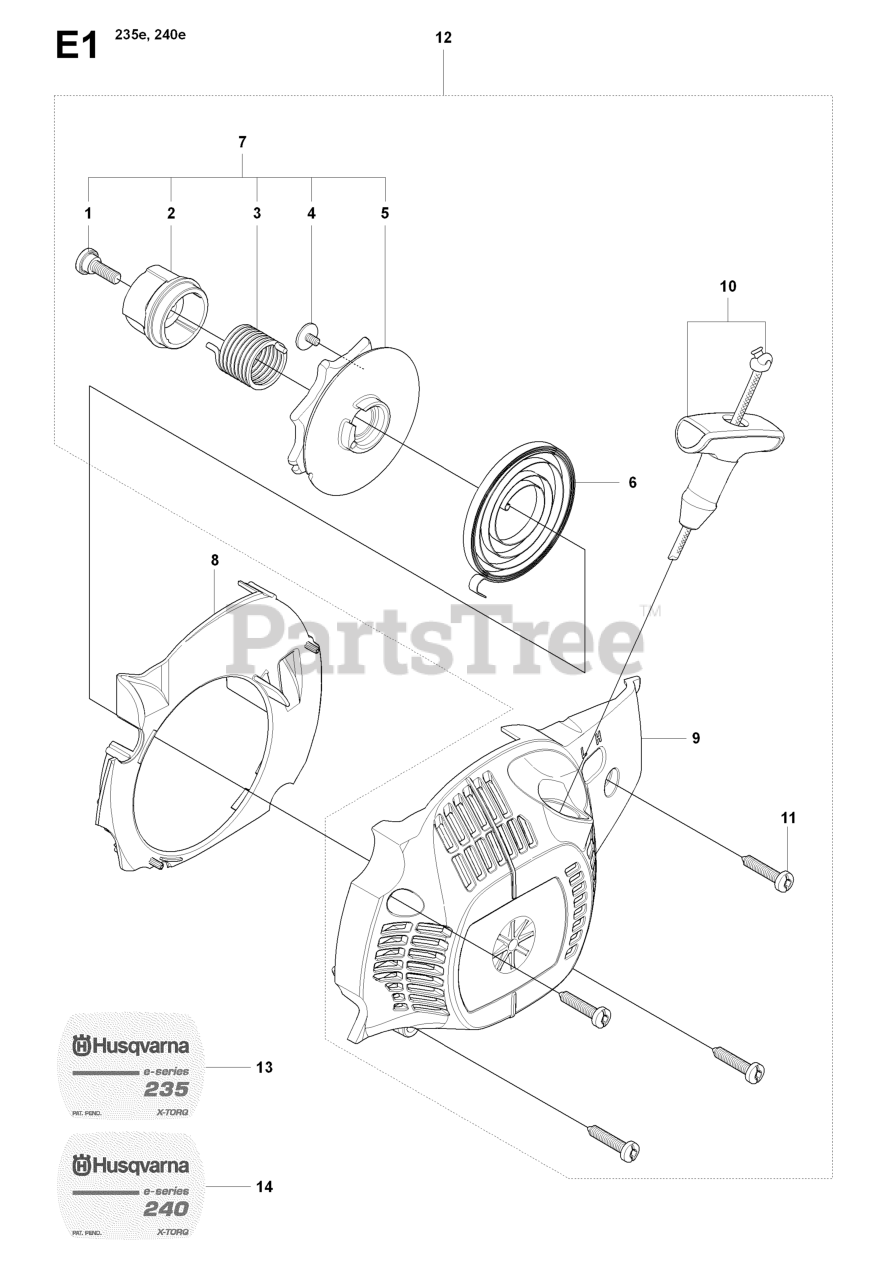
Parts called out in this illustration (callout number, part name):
1	SCREW SHOULDER
2	HUB STARTER EPS
3	SPRING EPS
5	PULLEY STARTER EPS
6	SPRING STARTER
7	KIT EPS STARTER
9	FAN HOUSING
10	STARTER ROPE W/HANDLE
11	SCREW M5.38-14X22.225MM
12	KIT COMPLETE EPS
13	DECAL 235E
14	DECAL 240E
